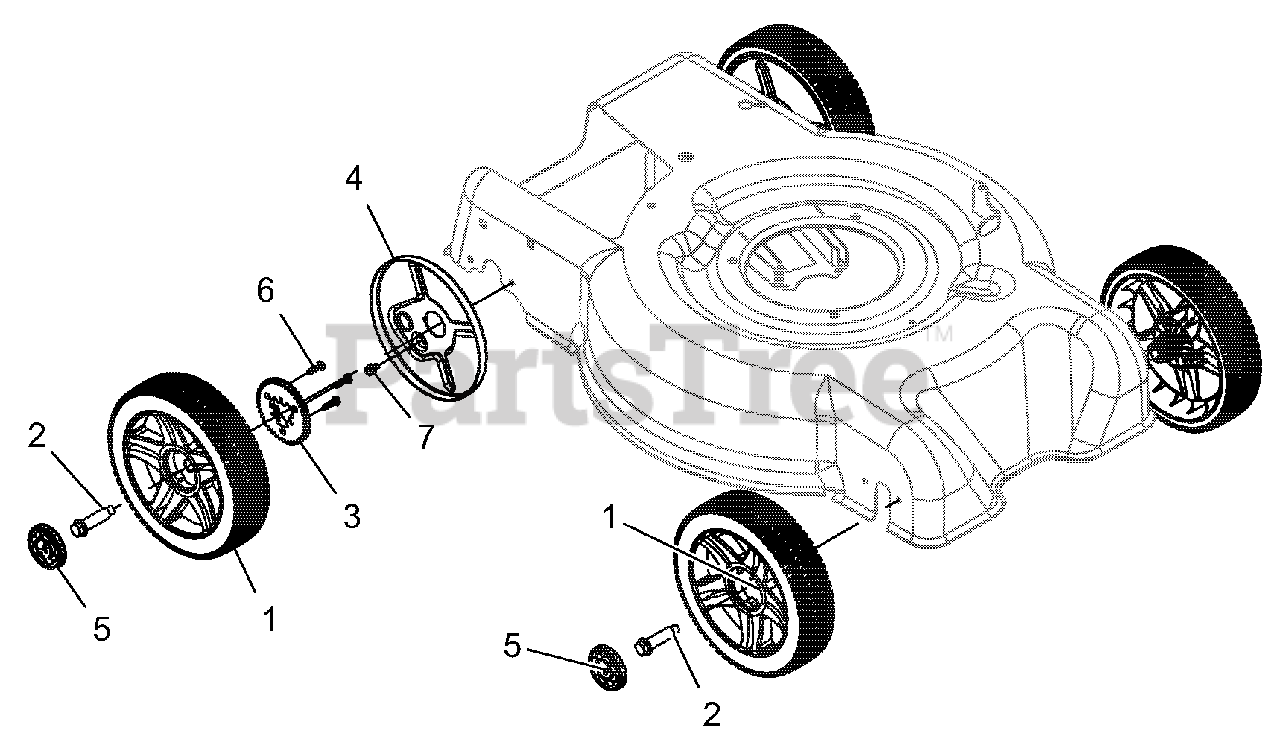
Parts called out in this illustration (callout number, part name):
1	ASSEMBLY, RAZOR WHEEL/BSHG
2	BOLT, WHEEL SHOULDER
3	GEAR, WHEEL
4	COVER, WHEEL
5	CAP, LM WHEEL HUB
6	SCR-TAP 12-14X.75PLSTITE @BLZC
7	@SCR-TAP .25-20X.37 HWH YWZ TR
